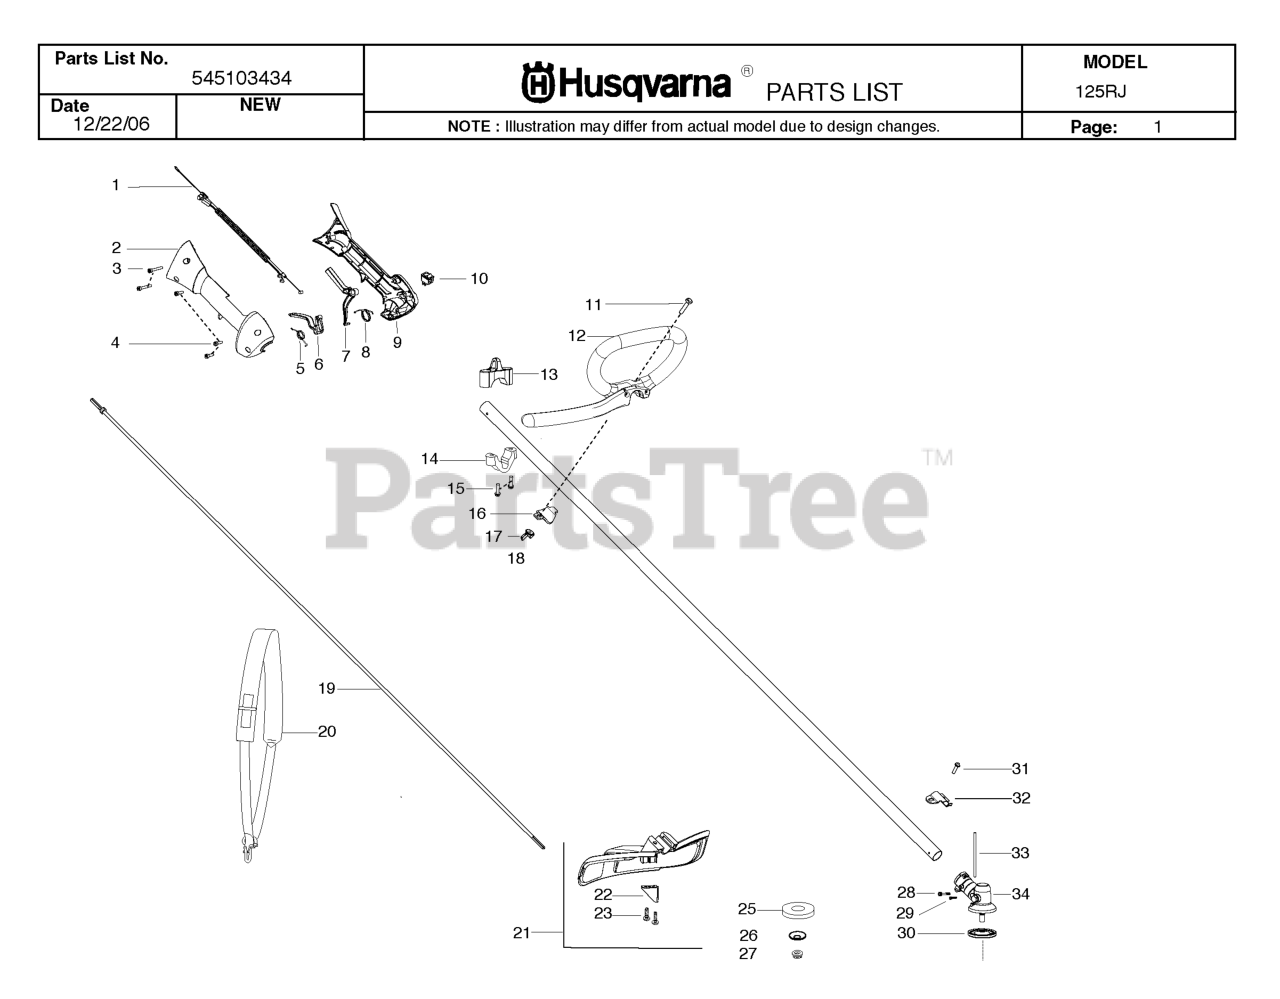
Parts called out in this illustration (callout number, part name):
1	%ASSY CABLE WIRE HARNESS
2	HOUSING-THROTTLE RH
4	SCREW M4 X 1.75 PT 16MM
5	SPRING TRIGGER
6	TRIGGER THROTTLE
7	THROTTLE LOCKOUT
8	SPRING LOCKOUT
9	HSG THROTTLE LH
10	KIT SWITCH
11	BOLT, TYPE 2
12	ASSY HANDLE JBAR
13	CLAMP HARNESS UPPER
14	CLAMP HARNESS LOWER
16	CLAMP ASSIST HANDLE
17	WINGNUT, TYPE 2
18	DRIVE SHAFT ASSY
19	FLEXSHAFT 57
20	Harness-w/o warning
20	Harness - Diagonal with sign
21	KIT COBI SHIELD
22	Limiter - Line
24	Blade - Grass
25	SUPPORTING CUP
26	SUPPORT FLANGE
27	GEARHEAD NUT - BRUSHCUTTER
28	SCREW - CARB. ADAPTOR
30	DRIVE DISC
31	SCREW 1/4-20 X 7/8 (TAP
32	BRACKET SHIELD STRAIGHT SHAFT
33	LOCKING PIN
34	ASSY GEARBOX
